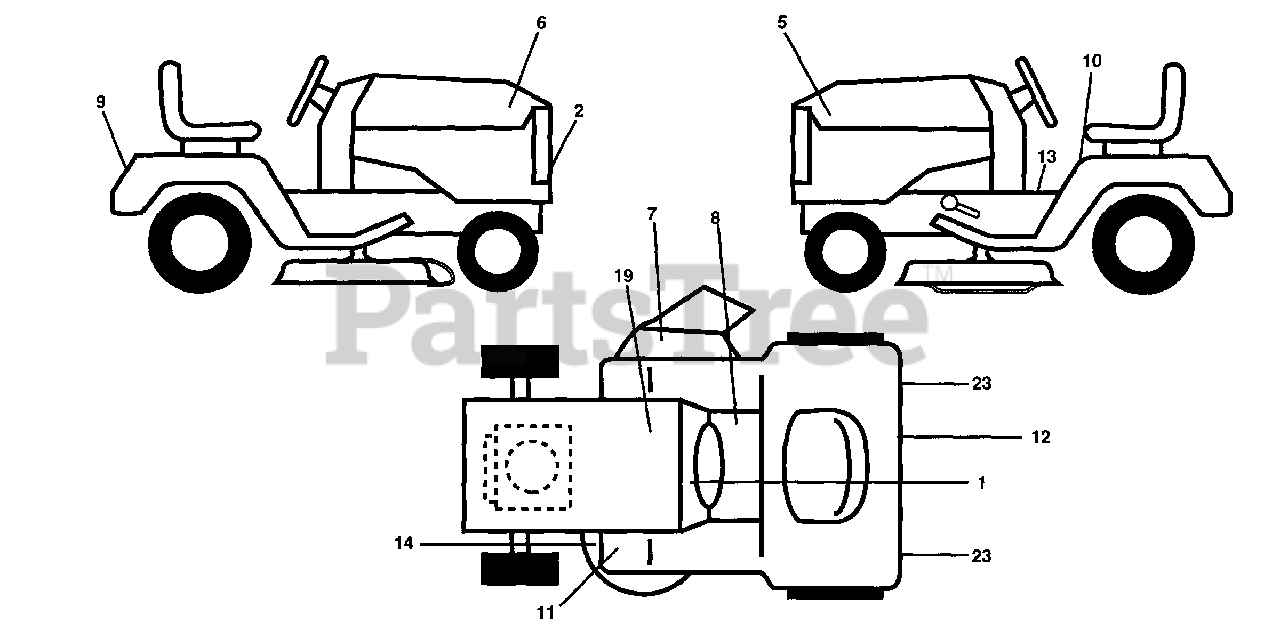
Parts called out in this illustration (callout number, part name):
1	Decal, Operating Instruction
2	Decal, Grille Husqvarna
5	Decal, Inst Hood LH GTH220 Hydro
6	Decal, Insrt Hood RH GTH220 Hydro
7	Decal, Warning Multi-Language
8	Decal, Brake Parking Saddle
9	Decal, Fender
10	Decal, Danger
11	Decal, Clutch/Brake
12	Decal, D-Bar Ctrl. Mvt Hyd YT/GT
13	Decal, Sdl Cold Start Hyd E/F
14	Decal, V-Belt Schematic
19	Decal, Battery
23	Reflector, Taillight
